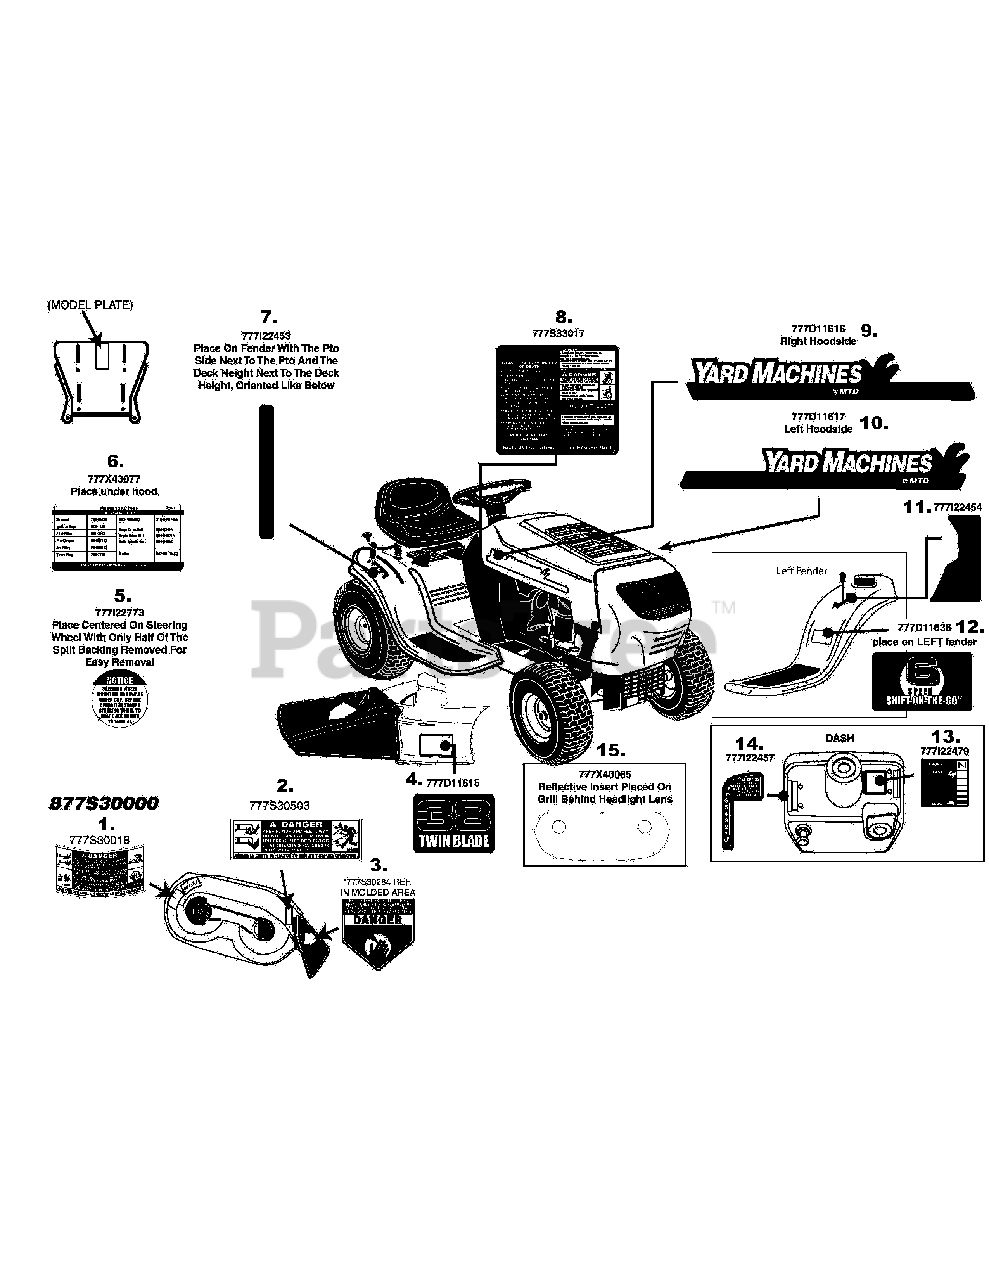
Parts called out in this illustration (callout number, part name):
1	LABEL-DECK SAFETY
2	LABEL-DANGER CHUTE
3	LABEL
4	LABEL-RIDER DECK YARD MACHINE 38"
5	LABEL-RIDER:SECURE WHEEL
6	LABEL-RIDER PARTS LIST 13AC762F
7	LABEL:RIDER LT-5 FENDER
8	LABEL-LT 5 TRANS COVER NO OCR
9	LABEL-RIDER HOOD RH YARD MACHINE
10	LABEL-RIDER HOOD LH YARD MACHINE
11	LABEL:RIDER LT-5 FENDER
12	LABEL-RIDER FENDER YARD MACHINE
13	LABEL: RIDER LT-5 THRT/CHK
14	LABEL:RIDER/LT-5 DASH
15	LABEL REFLECTOR
